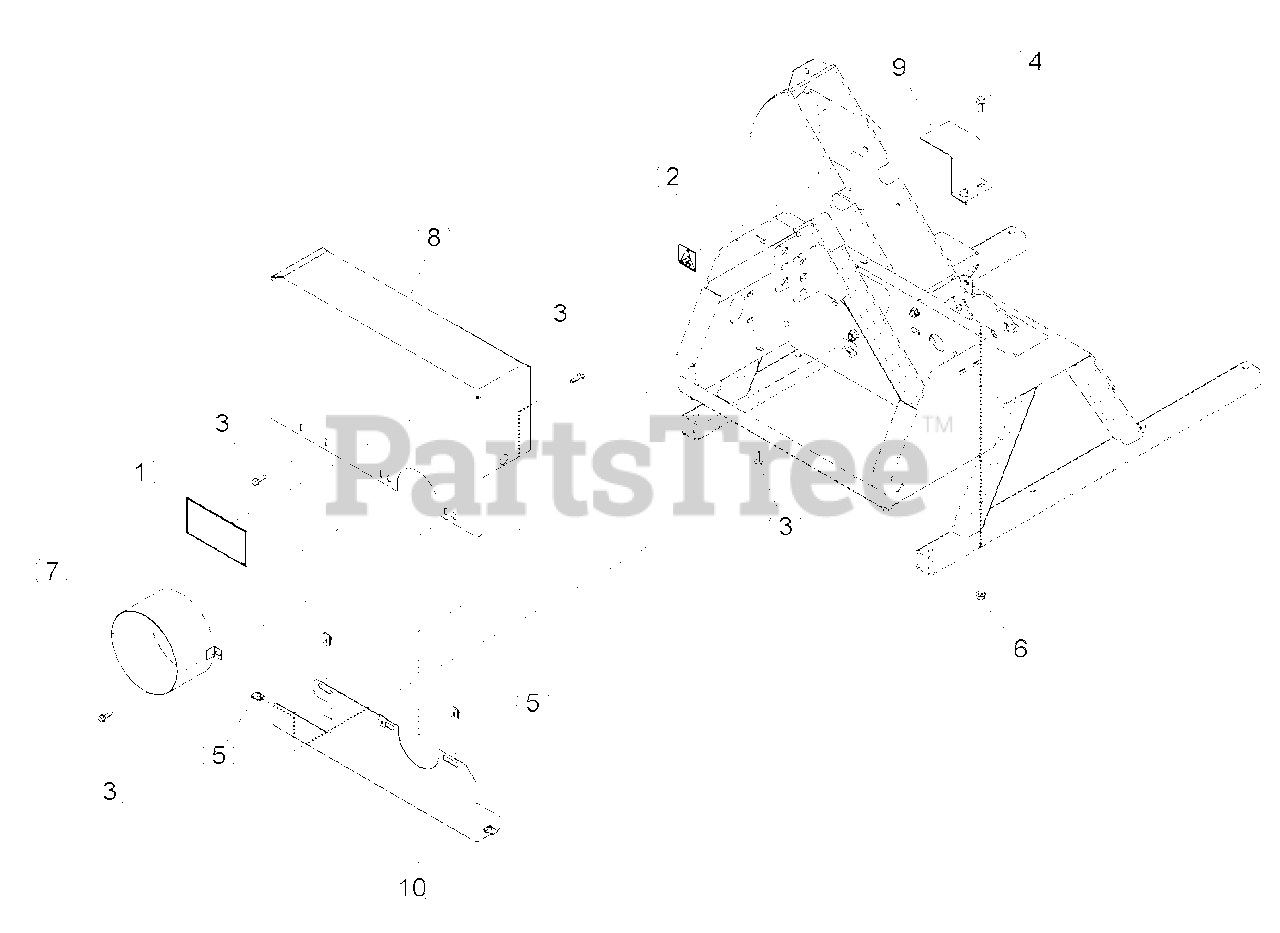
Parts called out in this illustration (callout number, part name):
1	DECAL, PTO DANGER ISO
2	DECAL, SHIELD DANGER ISO
3	BOLT, 5/16 X 1 FLANGE NC
4	BOLT, 3/8 X 1 FLANGE NC
5	NUT, 5/16"-18 TINNERMAN U-TYPE
6	NUT, 3/8-16 NYLOCK FLANGE
7	WELDMENT, PTO SHIELD
8	WELDMENT, UPPER BELT GUARD
9	COVER, JACKSHAFT
10	GUARD, LOWER BELT
